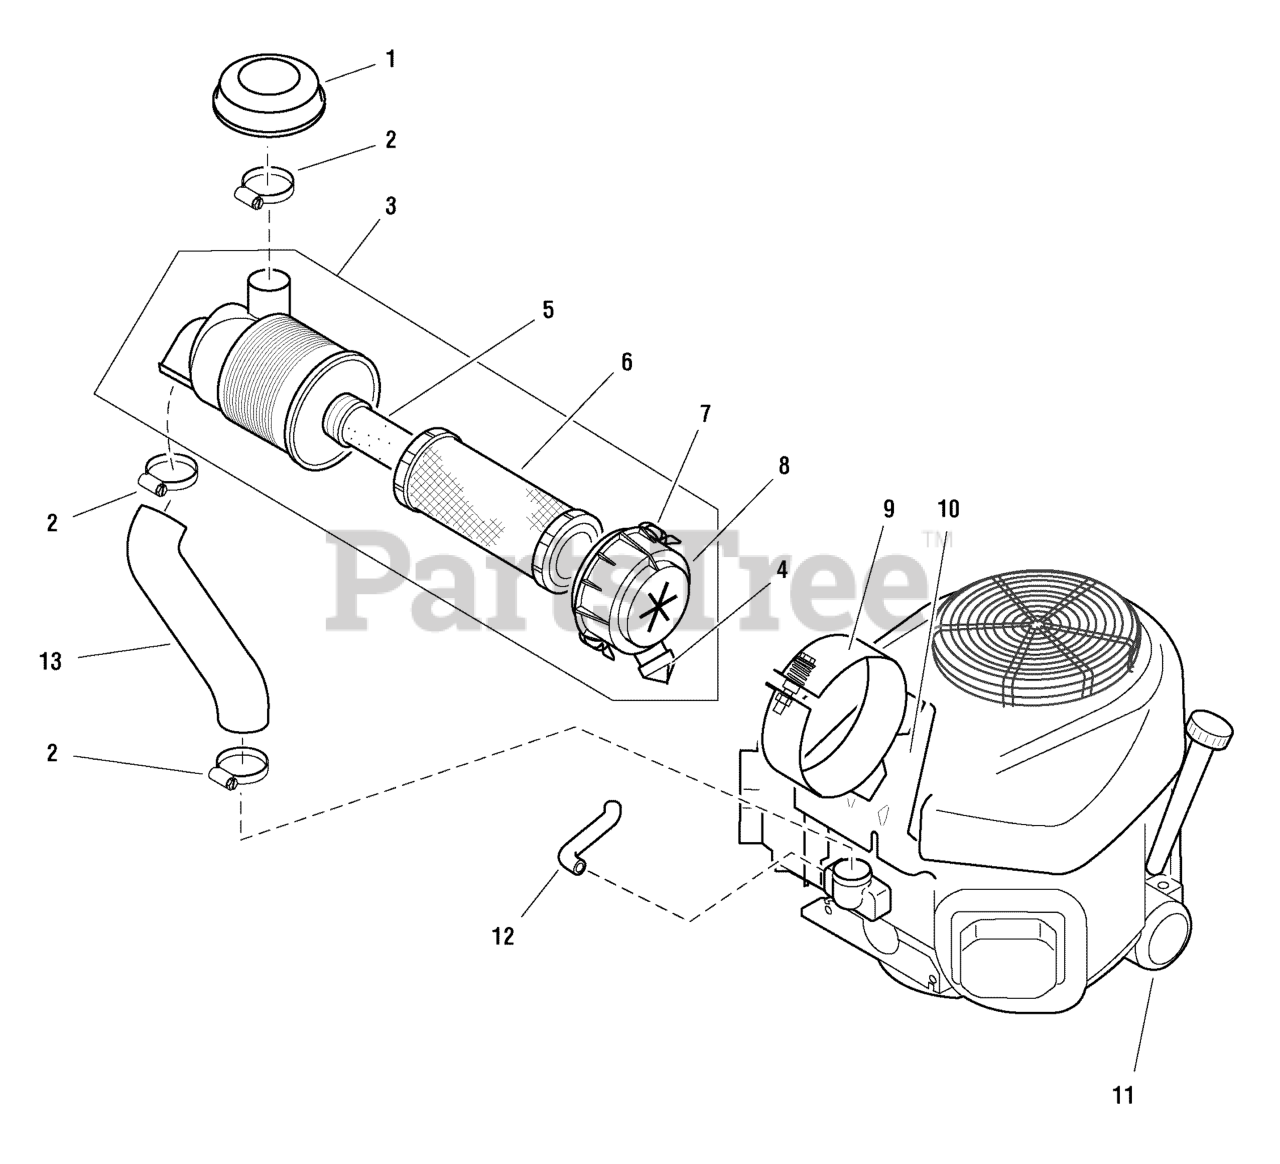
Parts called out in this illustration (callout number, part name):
1	RAIN CAP
3	AIR FILTER ASSEMBLY, Complete
4	RUBBER, Dust Valve
5	AIR FILTER, Secondary
6	AIR FILTER, Primary
7	CLAMP, Cap
8	CAP, FIlter Case
9	CASE BRACKET, Complete
10	BRACKET PLATE
11	OIL FILTER (49065-2078)
12	BREATHER TUBE
13	AIR INLET TUBE
